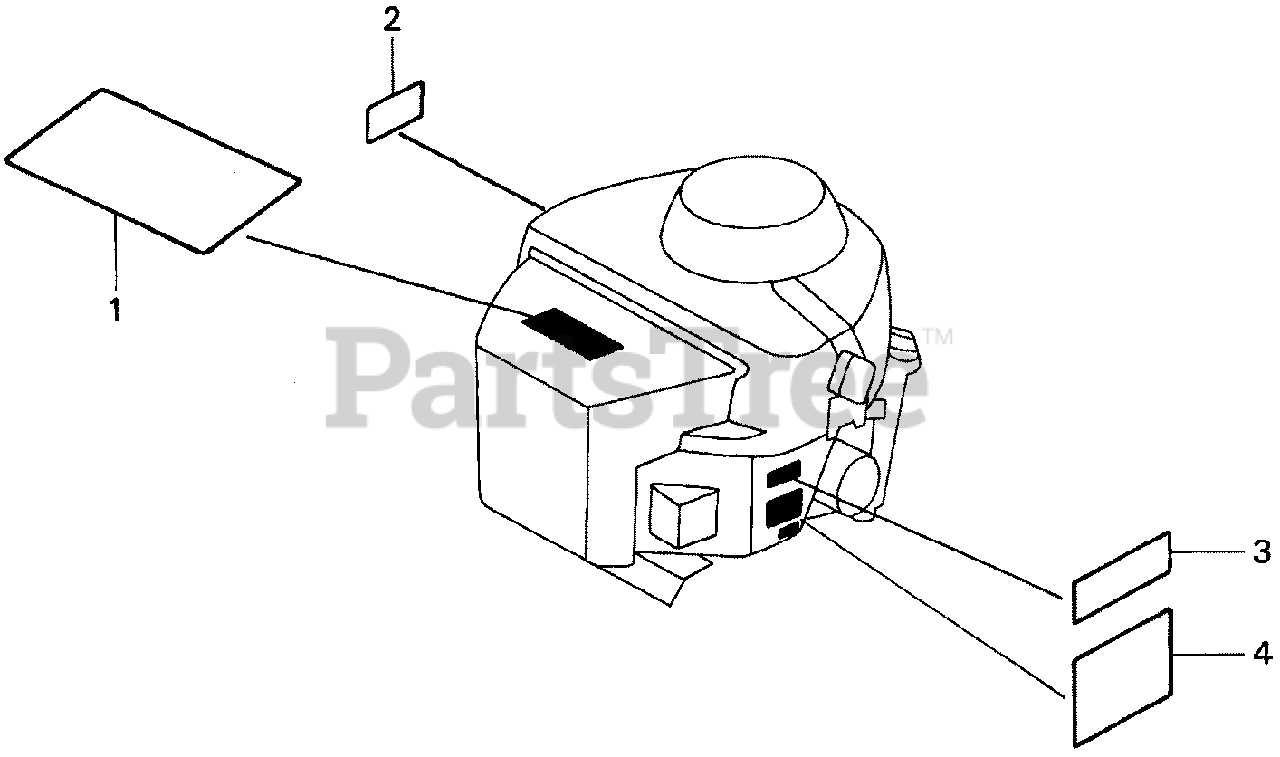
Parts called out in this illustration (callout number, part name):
1	MARK, EMBLEM (GXV610)
2	LABEL, FUEL CAUTION
3	LABEL, SPECIFICATION (GXV610)
4	LABEL, CAUTION
